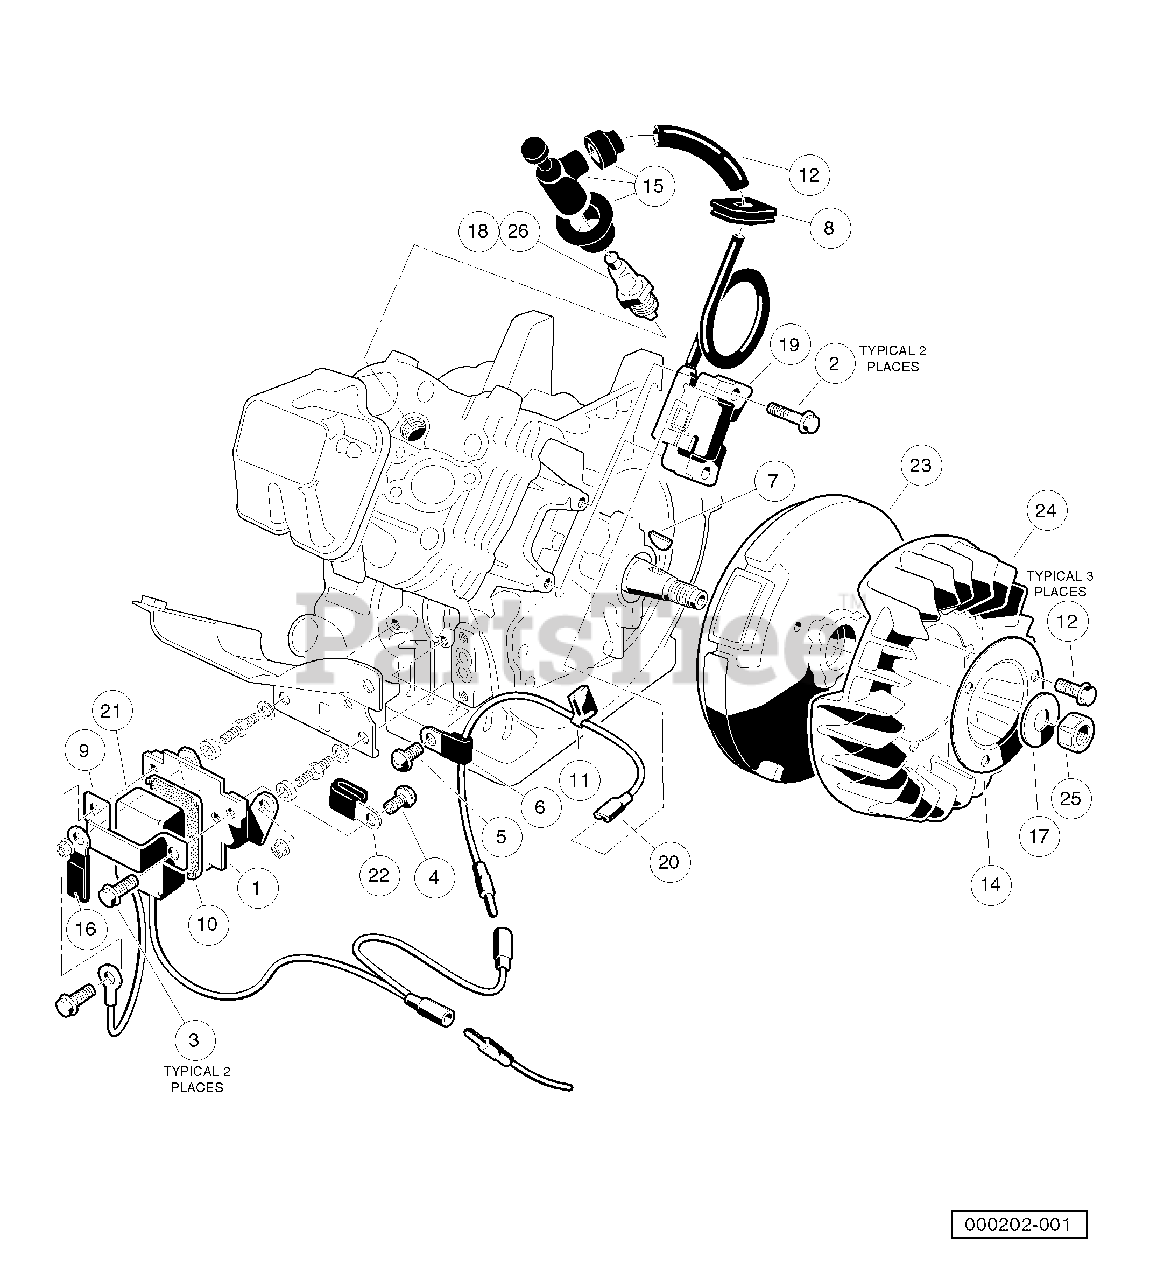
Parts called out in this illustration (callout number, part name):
1	Bracket, RPM Limiter
2	Bolt, Flange Head
3	Bolt, Flange Head, M6 x 1 x 12 mm
4	Screw, Pan WP Cross
9	Band, RPM Limiter Mount
10	Damper, RPM Limiter
12	Tube, 7mm X 10mm X 70mm
13	Bolt, Flanged
14	Plate, Flywheel Fan
15	Cap Asm Plug
17	Washer, Flat
18	Spark Plug, OHV
19	Coil, Ignition
20	Lead Wire Assy
21	Limited RPM
22	Clamp, Steel
24	Fan
25	Nut, Hex, 18 mm Fine
26	Spark Plug, OHV
